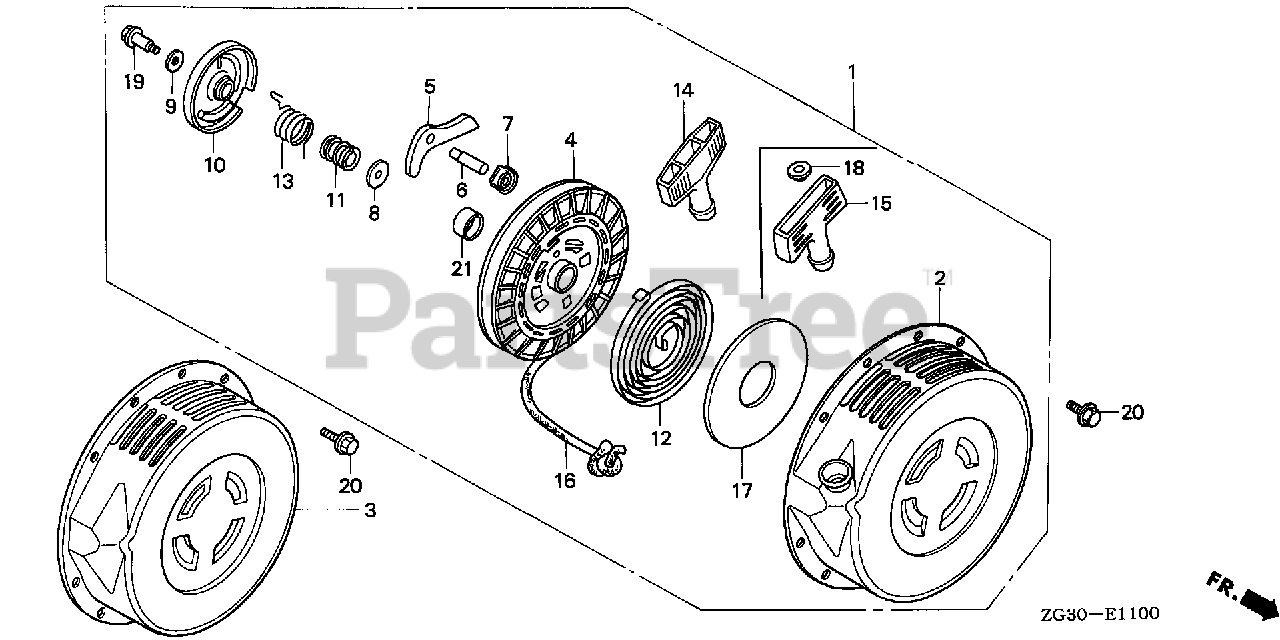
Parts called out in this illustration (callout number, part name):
1	STARTER ASSY., RECOIL *NH116M* (URBAN SILVER METALLIC)
2	CASE, STARTER *NH116M* (URBAN SILVER METALLIC)
2	CASE, STARTER
4	REEL, STARTER
5	RATCHET, STARTER
6	SHAFT, RATCHET
7	PLATE, GUIDE
8	PLATE A, FRICTION
9	PLATE B, FRICTION
10	COVER, STARTER REEL
11	SPRING, FRICTION (D=13.0MM / L=16.3MM)
12	SPRING, RETURN
13	SPRING, TORSION
14	GRIP, STARTER
15	GRIP, STARTER
16	ROPE, STARTER
18	REINFORCEMENT, GRIP
19	BOLT, REEL COVER (NOT AVAILABLE)
19	BOLT (6MM)
20	BOLT, FLANGE (6X8)
